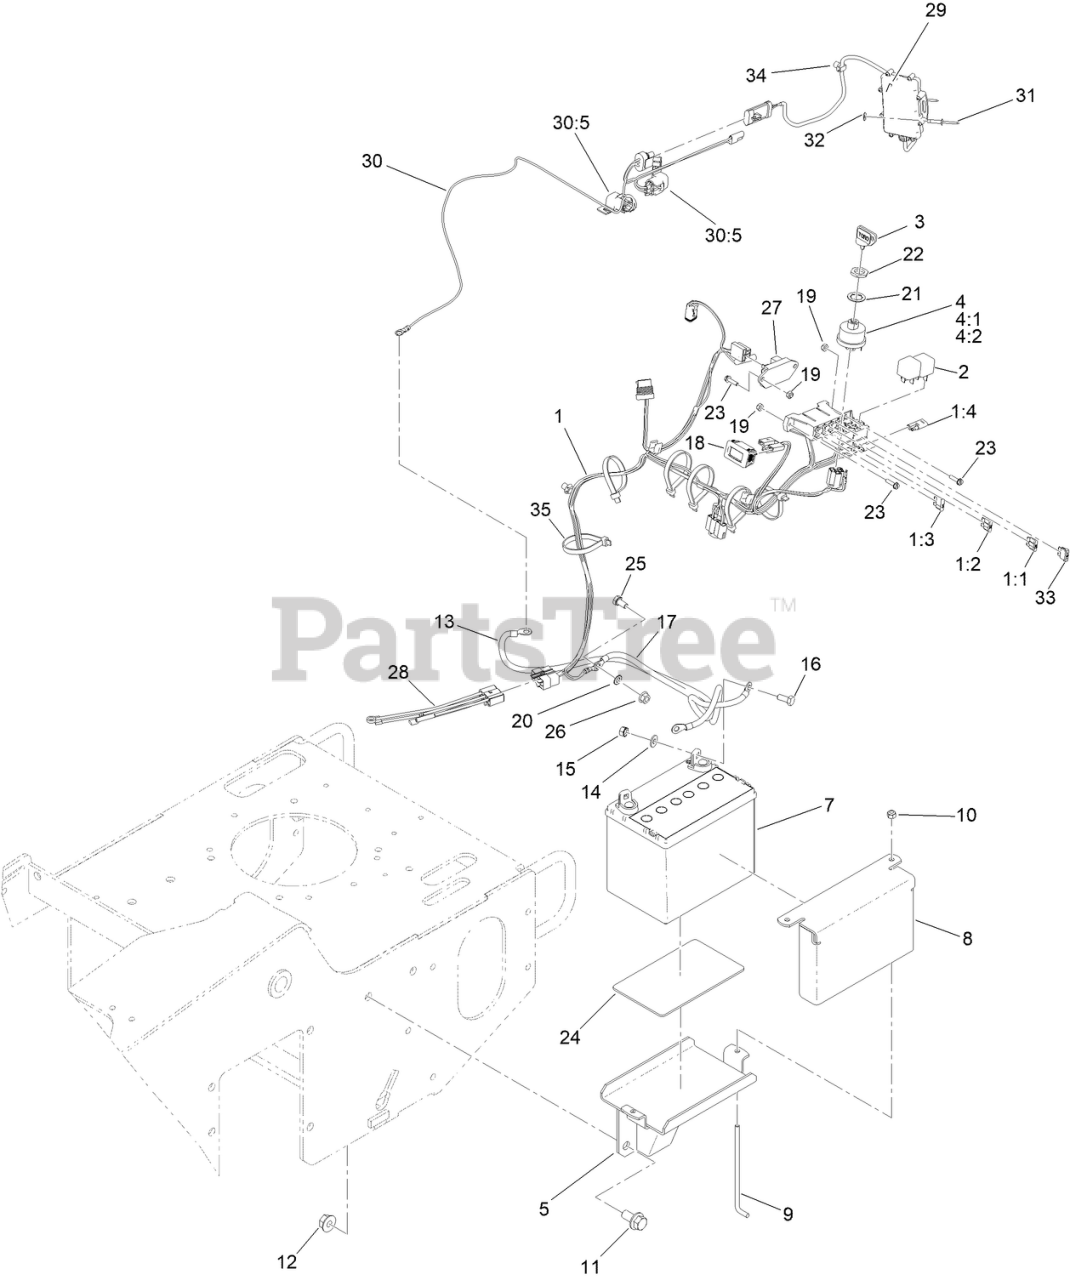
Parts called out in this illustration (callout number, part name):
1	HARNESS-WIRE
1:1	FUSE-BLADE, 30 AMP
1:2	FUSE-BLADE, 25 AMP
1:3	FUSE-BLADE, 20 AMP
1:4	CAP-PLUG
2	RELAY
3	KEY-IGNITION
4:1	WASHER-LOCK
4:2	NUT-HH
5	TRAY-BATTERY
8	PLATE-HOLD DOWN, BATTERY
9	HOLDOWN-BATTERY
10	NUT-LOCK, NI
11	SCREW-HHF
12	NUT-HHF
13	CABLE-BATTERY, POSITIVE
14	WASHER-FLAT
15	NUT-KEPS
16	SCREW-HH
17	CABLE-BATTERY, BLACK
18	HOURMETER
19	NUT-LOCK, NI
20	WASHER-LOCK
23	SCREW-HWH
24	PAD-SKID, ANTI
25	SCREW-HH
26	NUT-HF
27	MODULE-DELAY
28	HARNESS
29	GPS ASM
30	HARNESS-WIRE, GPS
30:5	COVER-FUSE, SINGLE
31	RIVET-POP
32	WASHER-PLAIN
33	FUSE-BLADE, 15 AMP
34	CLIP-TIE
35	TIE-CABLE
